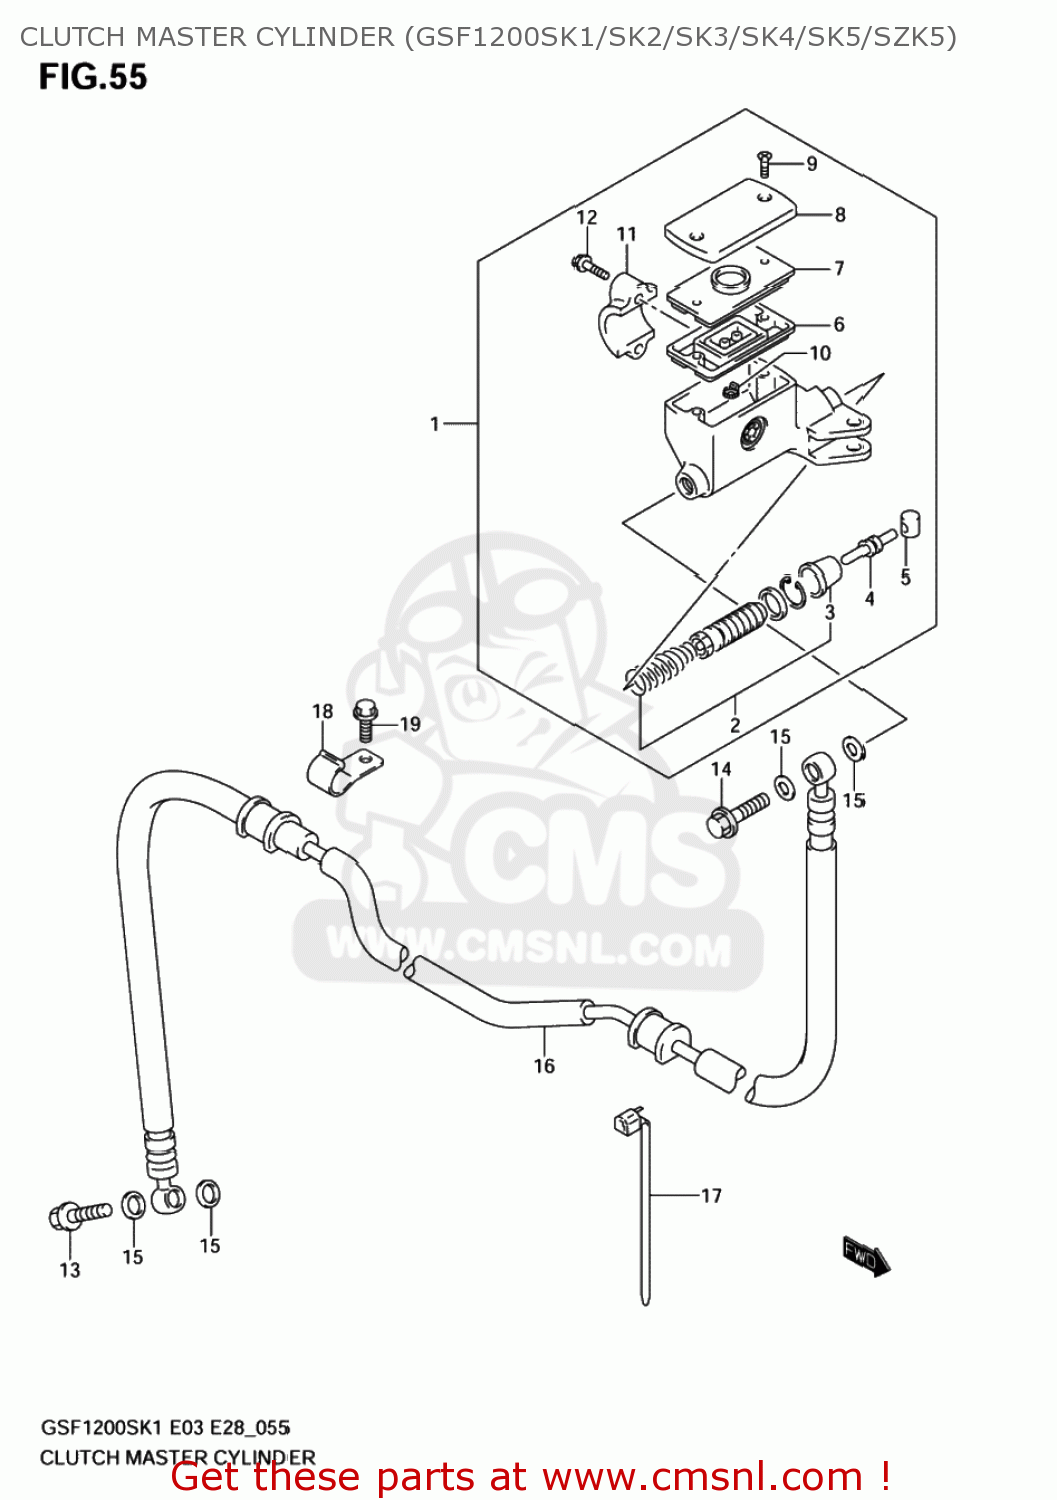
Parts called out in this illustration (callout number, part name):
1	CYLINDER ASSY,
2	PISTON & CUP SET
3	BOOT
4	PUSH ROD
5	BUSH
6	7
7	PLATE,DIAPHRAGM
8	CAP
9	SCREW
10	PROTECTOR
11	HOLDER
12	BOLT(6X22)
13	BOLT UNION
14	BOLT UNION
15	WASHER(10X15X1.5)
16	HOSE, CLUTCH
17	CLAMP(L:125)
18	CLAMP,CLUTCH HOSE NO.1
19	BOLT
